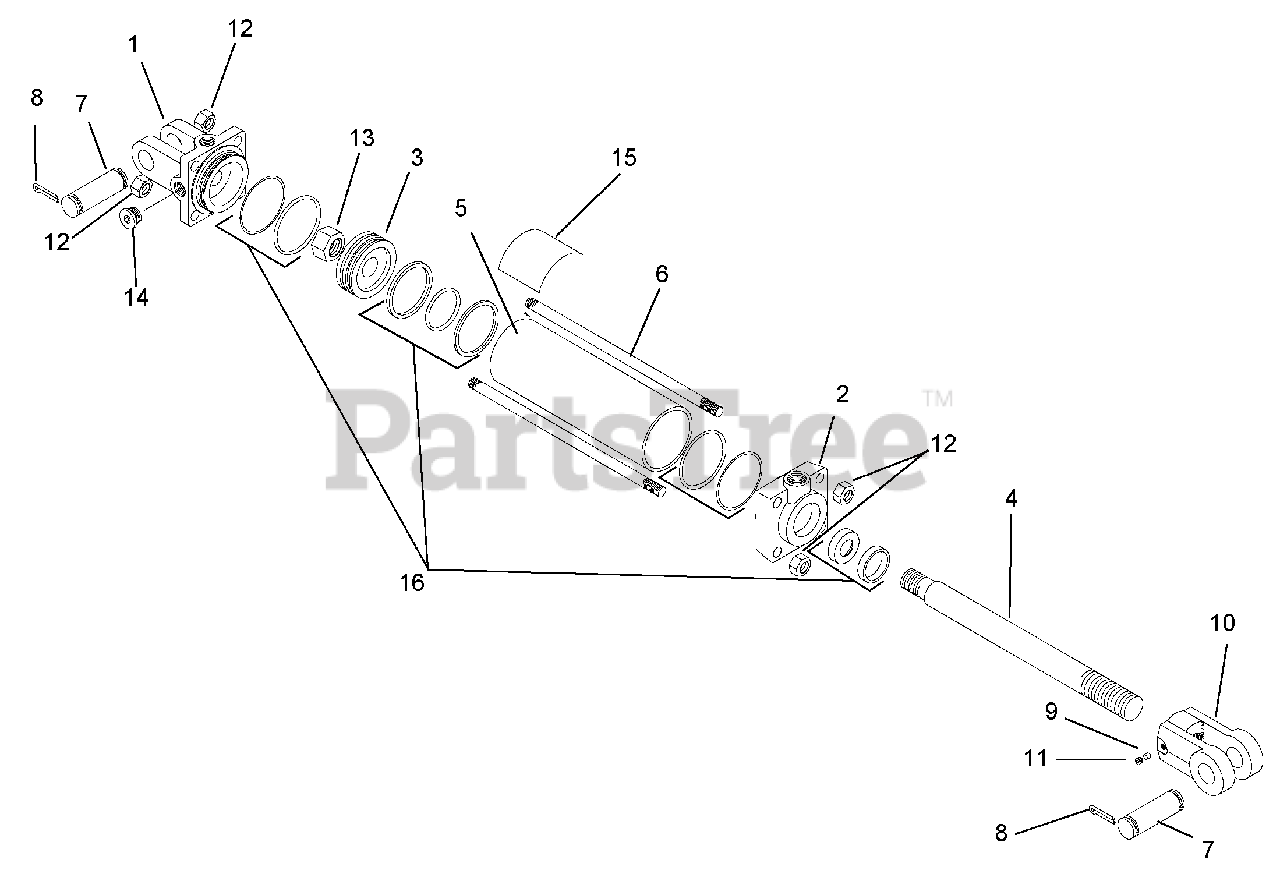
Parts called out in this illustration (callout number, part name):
1	Cap, Clevis 3.0
2	Cap, Rod 3.0 x 1.125 ORB
3	Piston 3.00 PSP 2, With Rings
4	Rod 1.25 x 12 (Side Units)
5	Tube, Cylinder 3.0 x 12 (Side Units)
6	Rod, Tie .50 x 12 (Side Units)
7	Pin, 1-Inch Diameter
8	Pin, Cotter .187 x 1.50
9	Lock, Nylon Thread
10	Clevis, Rod 1.25 x 1-14 (1 Pin)
11	Set Screw .38 x .50
12	Nut, Hex .50-13
13	Nut, Hex 1-14 UNF
14	Plug .75-16
15	Decal, Caution
16	Kit, Seal
